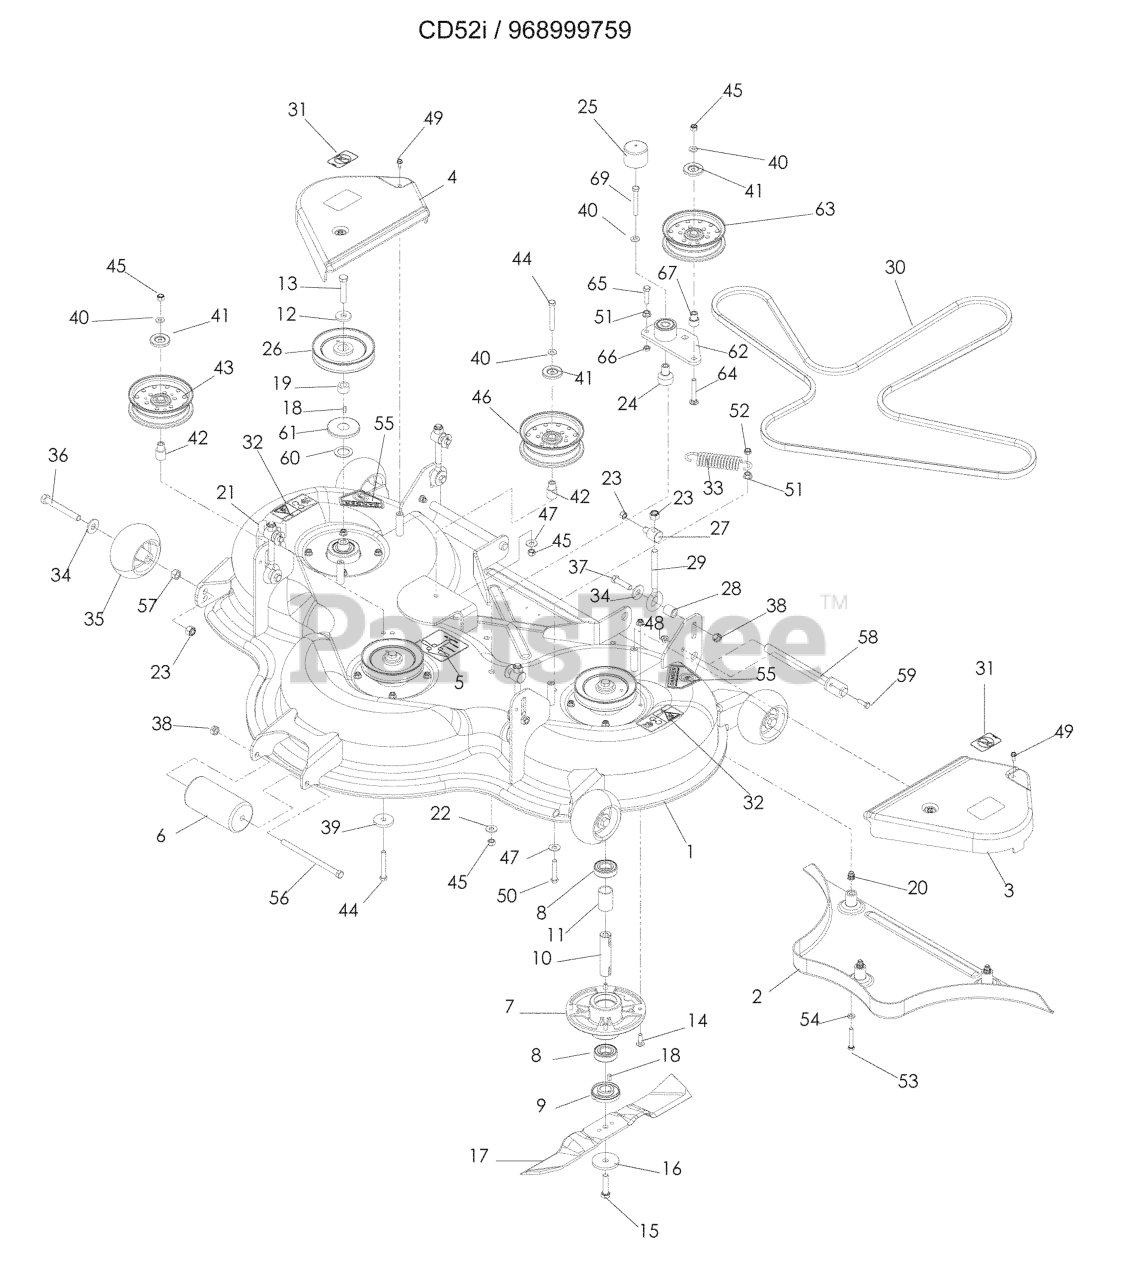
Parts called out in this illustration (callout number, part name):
1	DECK W/DECALS 52I HUS
3	BELT SHIELD LT
4	BELT SHIELD RT
5	DECAL, BELT ROUTING
6	ROLLER
7	BEARING HOUSING
8	BALL BEARING
9	BUSHING, BLADE
12	WASHER-.533IDX1.37OD
13	HCS M12 X 1.75 X 60 GR5 ZD
14	RHSNB 5/16C X 1
15	HCS M12 X 1.75 X 50 GR8.8 ZD
17	BLADE
19	KEY RETAINER
20	BLIND RIVET NUT
22	WASHER, SUPPORT
23	NUT 1/2-13 HEX NYLOC ZD
24	PIVOT, BEARING
25	CAP, VINYL
26	PULLEY, 52
27	SWIVEL, DECK HEIGHT ADJ
30	BELT, DECK - ESTATE
31	DECAL, NO STEP
32	DECAL, BELT DRIVE
34	WASH USS FLAT 1/2
35	GAUGE WHEEL
36	HCS 1/2-13 X 4 GR 5 ZD
37	HCS 7/16 - 14 X 1 3/4
38	NUT 7/16C CENTERLOCK
39	SPINDLE WASHER
40	WASHER, 3/8 THICK
41	DUST SHIELD
42	IDLER BUSHING
43	IDLER PULLEY
44	SCREW 3/8C X 2 3/4 HEX CAP
45	NUT 3/8-16 NYLOC
46	IDLER PULLEY (TALL)
47	WASHER 3/8 FLAT
48	5/16-18 NYLOC FLANGE NUT
49	SCREW 1/4 X 5/8
50	HCS 3/8C X 2
51	NUT 3/8C WHIZ
52	NUT HEX 3/8-16 NYLON, THIN
53	HCS M8 X 1.25 X 50 GR8.8 ZD
54	FLAT WASHER 5/16 SAE
55	DECAL, CPSC
56	HCS 7/16-14 X 7 GR5 ZD
57	NUT HEX 1/2
59	HCS 5/16C X 1
60	WASHER-1.06IDX1.63ODX.06
61	BOTTOM DUST CAP
62	ARM-IDLER W/BRG
63	IDLER PULLEY
64	CARRIAGE BOLT 3/8-16 X
65	HCS 3/8-16 X 1-1/2
66	NUT 3/8-16 HEX JAM
67	BUSHING, IDLER
68	CONTACT BELLSPR 1/2
69	SCREW, 1/2C X 3 HEX CAP
